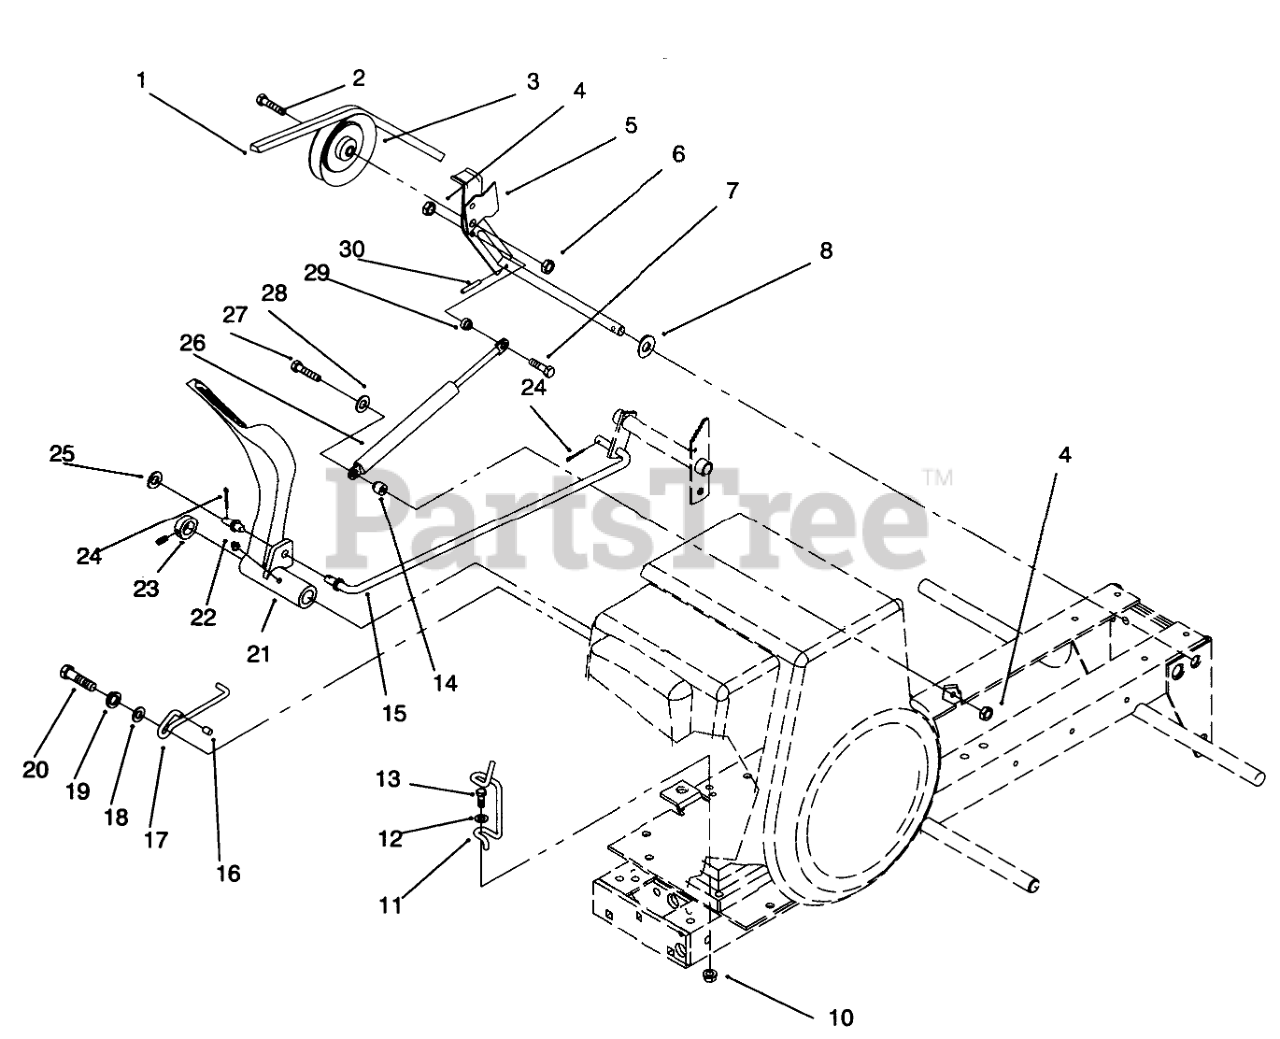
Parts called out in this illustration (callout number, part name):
1	BELT-V IN
2	BOLT-SPECIAL HEX
3	PULLEY-IDLER
4	NUT-LOCK, NI
5	Arm-Clutch Idler
6	NUT-HEX
7	Capscrew
8	SHIM-WASHER
14	SPACER-SHOULDER-.400
15	ROD-BRAKE
17	GUIDE BELT
18	WASHER-FLAT
19	WASHER-LOCK
20	SCREW-HH
21	Pedal-Brake
22	FITTING-GREASE
23	COLLAR
24	PIN-COTTER
25	WASHER-NYLON
26	ASS'Y-GAS SPRING
27	SCREW-HH
28	WASHER-FLAT
29	SPACER-SHOULDER-.200
30	PIN-SPIROL
